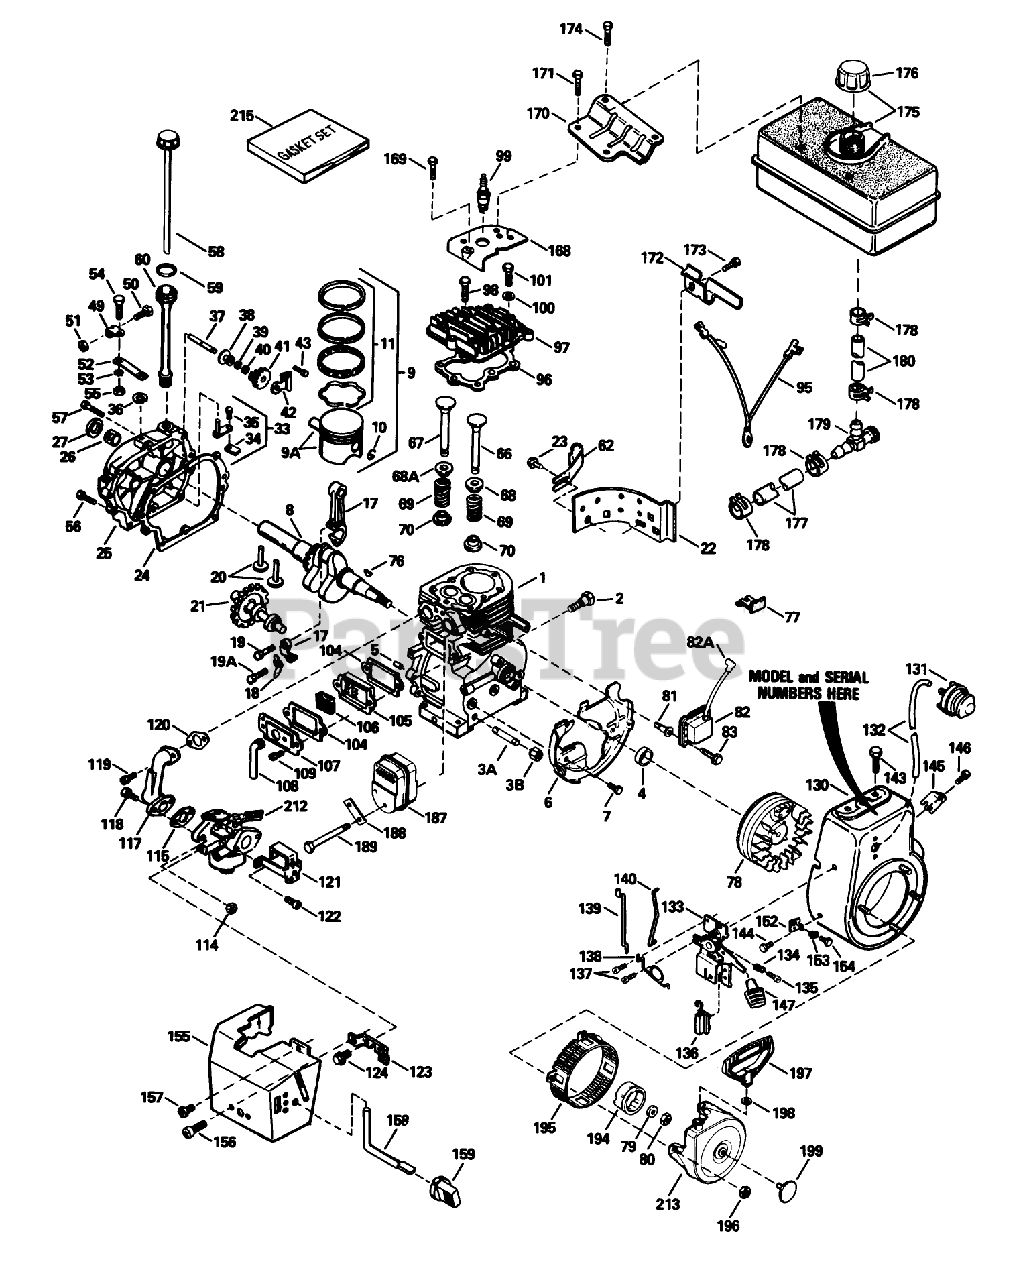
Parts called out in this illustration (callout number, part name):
1	Cylinder Asm (Includes 2, 20, 72)
2	Screw (1/4-20x1/2)
3A	Nipple-Pipe
3B	Cap-Pipe
4	Seal-Oil
5	Pin-Dowel
6	Baffle-Blower Housing
7	Screw (1/4-20x19/32)
8	Crankshaft
9	Piston, Pin Ring Assy.(Std.) (Incl. Ref. #24A, 25 26)
9A	Piston Pin Assy. (Std.) (Incl. Ref. #26)
11	Ring Set (Std.)
17	Rod Assy., Connecting (Incl. Ref. #28 28A)
18	Dipper-Oil
19	Bolt-Rod
19A	Bolt-Rod
20	Lifter-Valve
21	Camshaft (MCR)
22	Extension-Housing, Blower
23	Screw
24	Cylinder Cover Gasket
25	Cover-Cylinder (Includes 71, 75, 80)
26	2025A77 WIZARD ROTA
27	Seal-Oil
33	Rod, Governor (Incl. Nos.62 63)
34	Yoke-Governor
35	Screw (6-40x5/16)
36	Ring-Retaining
37	Shaft-Governor
38	Spool-Governor
39	Washer
40	Ring-Retaining
41	Gear Assy., Governor (Incl. Ref. #45)
42	Bracket-Gear, Governor
43	Screw (10-24x1/2)
49	Clamp-Lever, Governor
50	Screw
51	Nut-Lock
52	Lever-Governor
53	Washer-Lock
54	Screw
55	Nut-Lock
56	Screw (1/4-20x1-11/16)
57	Screw (1/4-20x1-3/16)
58	Dipstick
59	O-Ring
60	Tube-Fill, Oil
62	Clip-Tube, Fill
66	Valve, Exhaust (Standard)(Incl. No. 9)
67	Valve, Intake (Std.) (Incl. Ref. #58)
68	Cap-Spring, Valve
68A	Seal-Intake Valve
69	Spring-Valve
70	Keeper-Spring, Valve
76	Key-Flywheel
77	Clip-Wire
78	Flywheel (W/Ring Gear)
79	Washer-Belleville
80	Nut-Flywheel
82	Solid State ASM
82A	Cover-Spark Plug
83	Screw
95	Ground Wire
96	Gasket-Cylinder Head
97	Head Cylinder
98	Screw (5/16-18x1-1/2)
99	Spark Plug-Resistor (R J19 L M)
100	Washer-Flat
101	Screw (5/16-18x1-25/32)
104	Gasket-Cover, Valve
105	Body-Breather
106	Element-Breather
107	Cover-Valve
108	Tube-Breather
109	Screw
114	Nut and Lock Washer (1/4-28)
115	Gasket-Carburetor To Intake Pipe
117	Pipe-Intake
118	Screw (1/4-28x1)
119	Screw (T-30, 5/16-18x1-3/32)
120	Gasket-Pipe, Intake
121	Bracket-Choke
122	Screw (10-32 x 1/2)
123	Bracket-Carburetor
124	Screw (8-32x27/64)
130	Housing-Blower
131	Primer-Asm
132	Line-Primer
133	Bracket-Control (Includes 19, 203, 204, 206)
134	Spring-Compression
135	Screw
136	Terminal
137	Screw (10-32 x 1/2)
138	Spring-Throttle
139	Link-Governor
140	Link-Throttle
143	Screw (5/16-18x3/4)
144	Screw
145	Screw
146	Screw (8-32 x 3/8)
147	Knob-Control
152	Bracket
153	Grommet
154	Screw (8-32 x 3/8)
155	Cover-Carburetor
156	Screw (10-32 x 3/8)
157	Screw (10-32x1/2)
158	Rod-Choke
159	Knob-Control
168	Cover-Cylinder Head
169	Screw (1/2-20x5/8)
170	Bracket-Tank, Fuel (Black)
171	Screw
172	Bracket-Tank, Fuel
173	Screw (1/4-20x19/32)
174	Screw (1/4-15x7/8)
175	Tank-Fuel (Includes 292, 301)
176	Cap-Fuel
177	Line-Fuel
178	Clamp-Line, Fuel
179	Valve-Shut Off
180	Line-Fuel (8.62)
187	Muffler
188	62513 SNWTHWR W/284
189	Screw
194	Cup-Starter
195	Screen-Starter
196	Nut and Lock Washer (1/4-28)
197	Handle-Starter, Mitten Grip
198	Washer
199	Plug Starter
212	Carburetor (Incl. Ref. #184)
213	Starter-Rewind
215	Gasket Set (Incl. items marked *)
